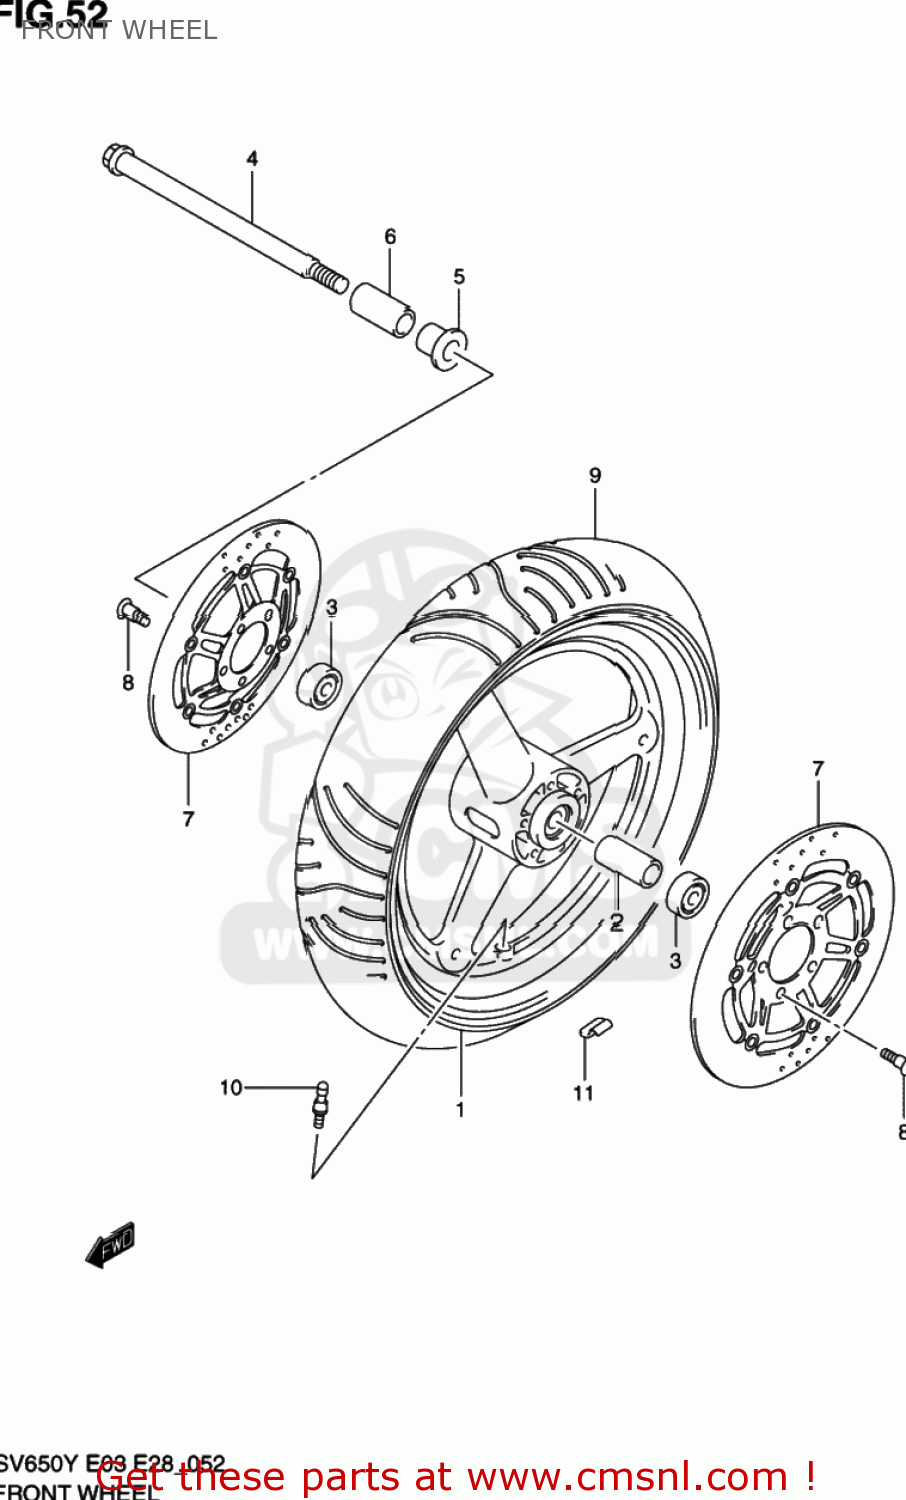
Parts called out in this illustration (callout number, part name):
1	WHEEL,FRONT (17XMT3.50)(
2	SPACER(17.5X22.5X73)
3	BEARING
4	AXLE,FR
5	SPACER,FR AXLE,R
6	SPACER,FR AXLE,R
7	DISC,FR BRAKE
8	BOLT 8X33
9	TIRE 120/60 ZR17 (55W)
10	VALVE ASSY,WHEEL RIM(TR412)
11	BALANCER,WHEEL (10G)
